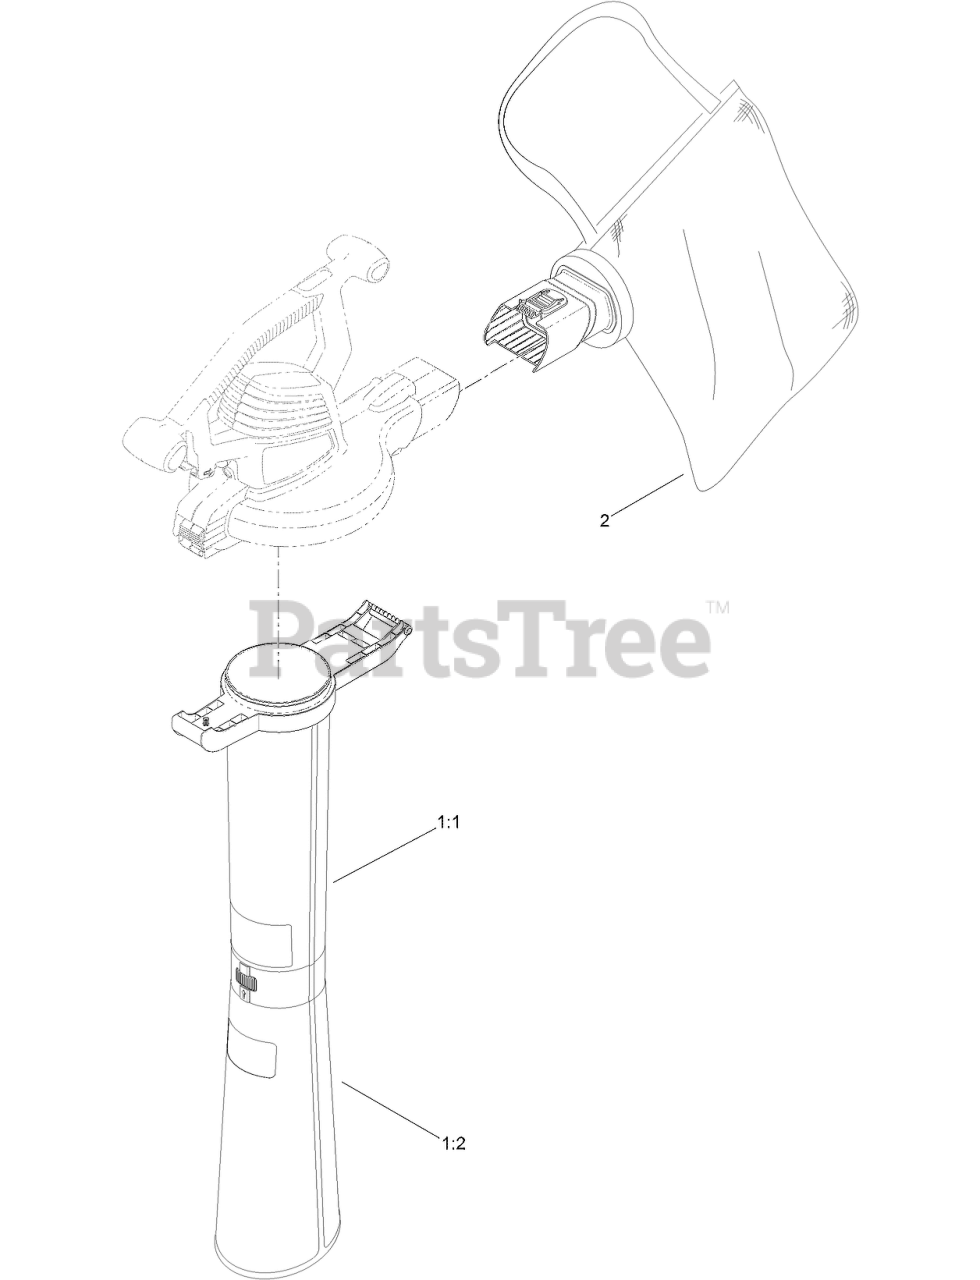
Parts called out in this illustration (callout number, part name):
1:1	TUBE-VACUUM, UPPER
1:2	TUBE-VAC, LOWER
2	BAG ASM
